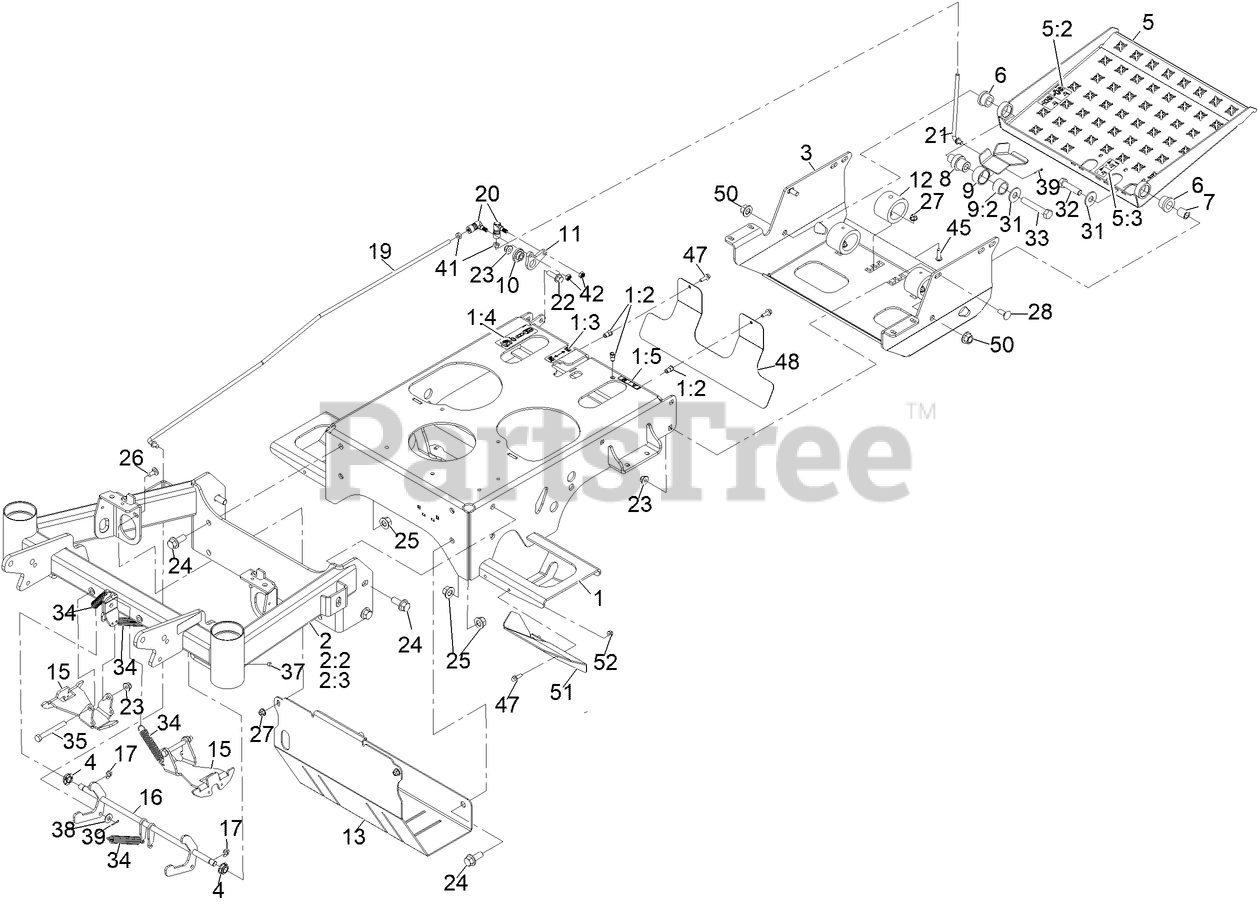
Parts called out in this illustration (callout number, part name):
1	FRAME-REAR, JR36
1:2	NUT-CLINCH,HEX
1:3	DECAL-BRAKE, PARKING
1:4	DECAL-STRAINER
1:5	Decal-Hot Surface
2	FRAME-FRONT, JR36
2:2	BUSHING-FLANGE
2:3	DECAL-WARNING, PINCH POIN
3	MOUNT-FOOTPLATE, JR36
4	BEARING-SPHERICAL
5	FOOT PLATE W/DECALS
5:2	Decal-Lock, Caster
5:3	Decal-Spray Foot Button
6	BUSHING-RUBBER
8	PIVOT-PEDAL, CASTER
9	PEDAL-LOCK, CASTER
9:2	BUSHING
10	PIVOT-FLANGE
11	CRANK-DEFLECTOR
12	BUMPER-ISOLATOR
13	GUARD-MUFFLER
15	ARM-LOCK, CASTER
16	CRANK-LOCK, CASTER
19	LINKAGE-LOCK, CASTER
20	Ball Joint-Quick Disconnect, SS
21	LINKAGE-PEDAL, CASTER
22	SCREW-HHF
23	Nut-Hex Flange
24	SCREW-HHF
25	NUT-HEX FLANGE
26	SCREW-CARR
27	Nut-Hex Flange
28	SCREW-CARR
31	WASHER-FLAT
32	SCREW-HH
33	SCREW-HH
34	SPRING-EXTENSION
35	SCREW-HH
38	FLAT WASHER, 5/16 NOM,ST
39	COTTER PIN 5/64X3/4 18-8
41	Nut-Hex
42	NUT-LOCK, NI
45	SCREW-HSBH
47	Screw-HHF
48	DEFLECTOR-HEAT
50	Nut-Lock 1/2-13
51	SHIELD-TANK HEAT
52	Nut-Hex Flange
